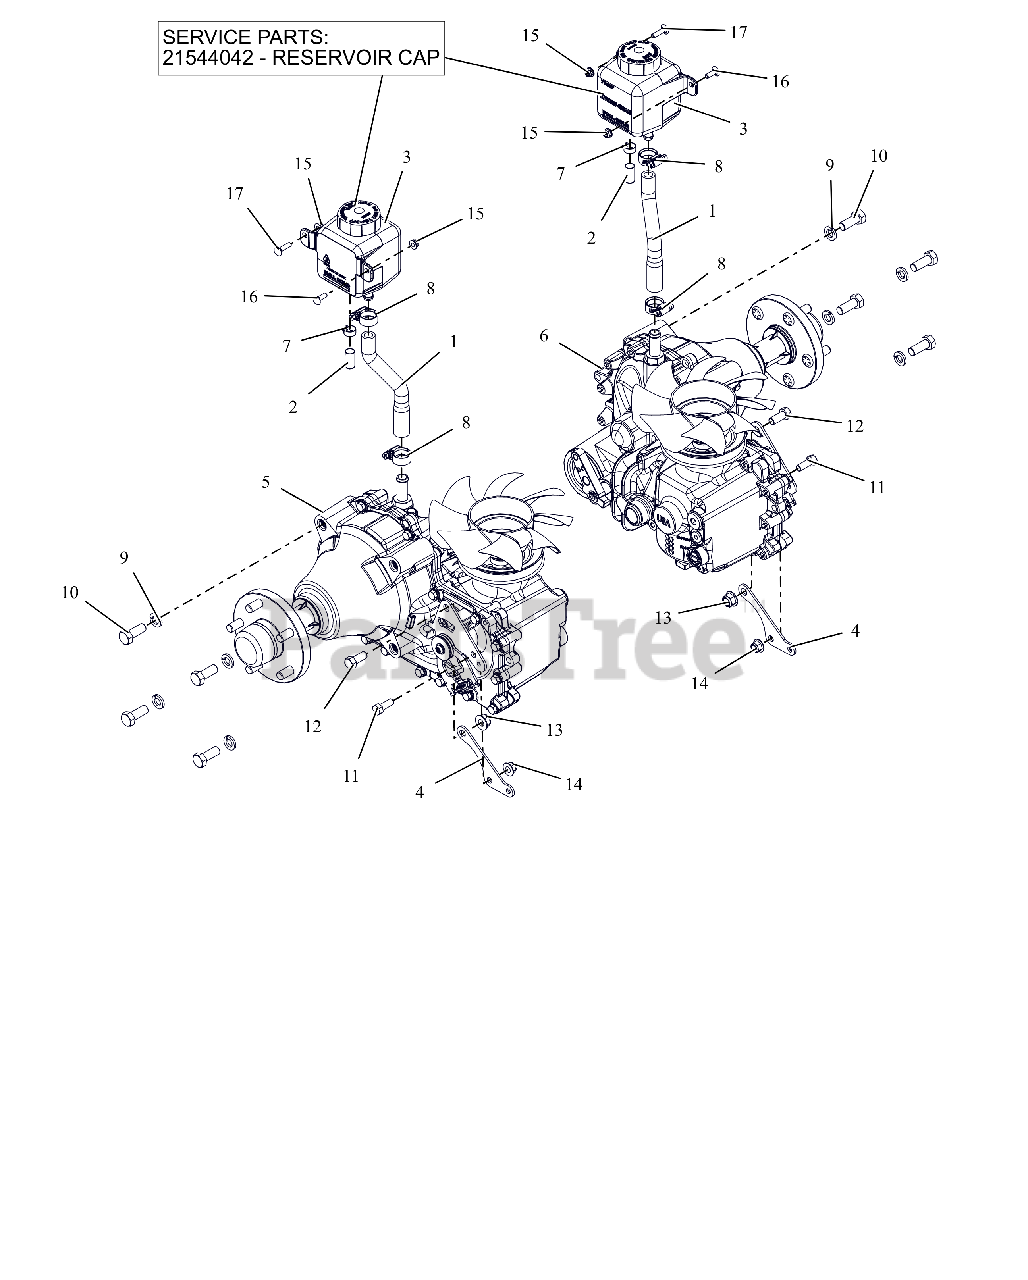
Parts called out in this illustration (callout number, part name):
1	HOSE,PT200/400 TRANS OVERFLOW
2	CAP, .50 BARBED FITTING
3	TANK, HYDRO OVERFLOW 700 ML
3	CAP, HYDRO RESERVOIR REPLAC.
4	DRV CNTRL LINKAGE MTG BRKT-BLK
5	TRANSAXLE, RH HG ZT-5400
6	TRANSAXLE, LH HG ZT-5400
7	CLAMP, .62 SPRING
8	CLAMP,.88 DIA. HOSE
9	WSHR,LK-REG .500X.125 ZCC
10	BLT,HEX .50-13X1.25 G5 ZCC
11	BLT,HEX .38-16X1.00 G5 ZCC
12	BLT, HEX 0.4375-14X1 GR5 ZCC
13	NUT,NYL-FLG .44-14 GF ZCC
14	NUT,NYL-FLG .38-16 GF ZCC
15	NUT,NYL-FLG .25-20 GF ZCC
16	BLT, RHSN .25-20X.750 G5 ZCC
17	BLT, RHSN .25-20X1.00 G5 ZCC
